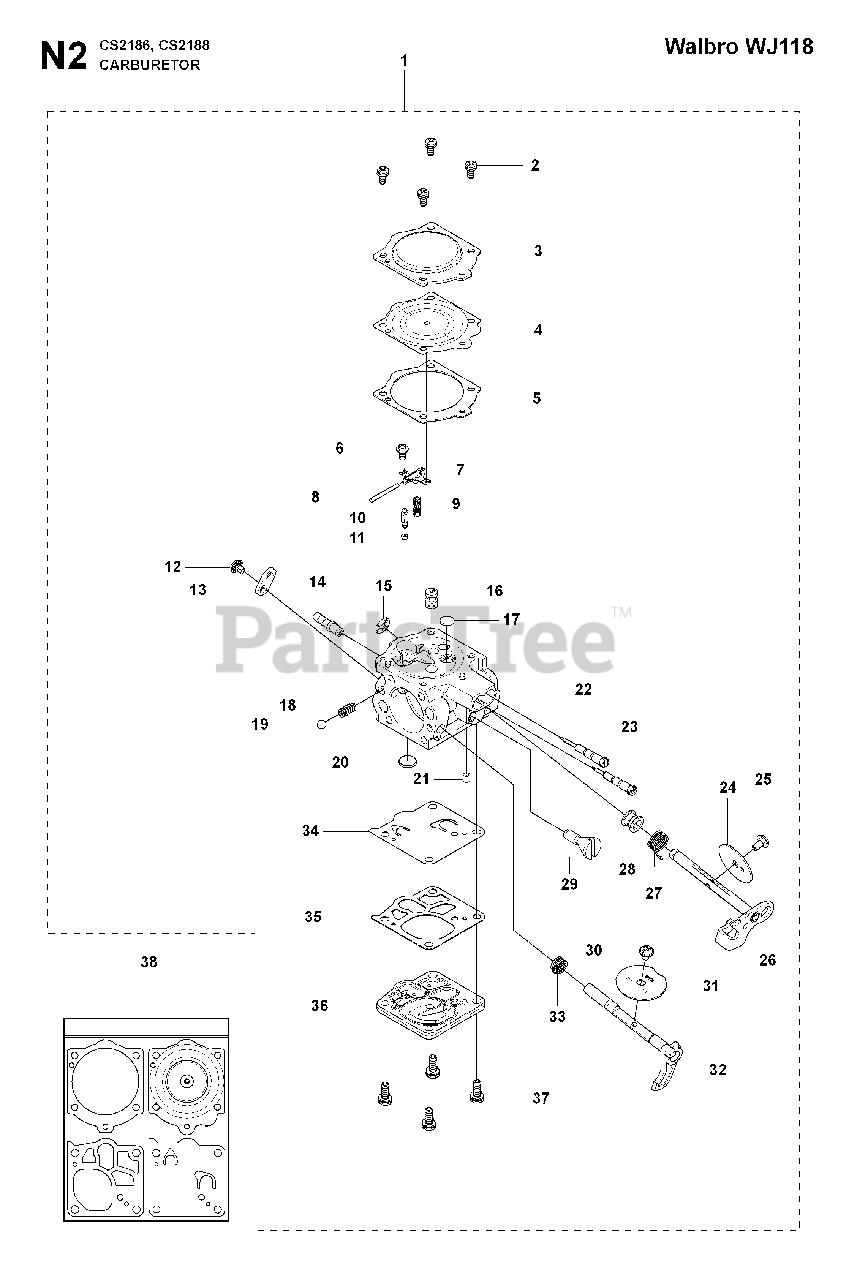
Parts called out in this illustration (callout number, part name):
1	CARBURETOR
2	SCREW W/ WASHER
3	DIAPHRAM COVER
4	MAIN DIAPHRAGM
5	GASKET
6	SCREW
7	LEVER
8	PIN
9	SPRING
10	INLET NEEDLE
11	SEAT IN VALVE PLATED
12	SCREW.
13	LEVER CHOKE
14	FITTING FUEL INLET
15	E CLIP
16	NOZZLE
17	PLUG WELCH
18	SPRING 394
19	BALL 394
20	FUEL INLET SCREEN
21	PLUG FRICTION
22	NEEDLE
23	NEEDLE
24	THROTTLE FLAP
25	SCREW
26	SHAFT ASSY THROTTLE
27	%SPRING
29	SCREW
30	SCREW
31	CHOKE FLAP
32	SHAFT ASSY
33	SPRING CHOKE
34	DIAPHRAM PUMP
35	GASKET
36	COVER PUMP
37	SCREW W/ WASHER
38	DIAPHRAGM SET
